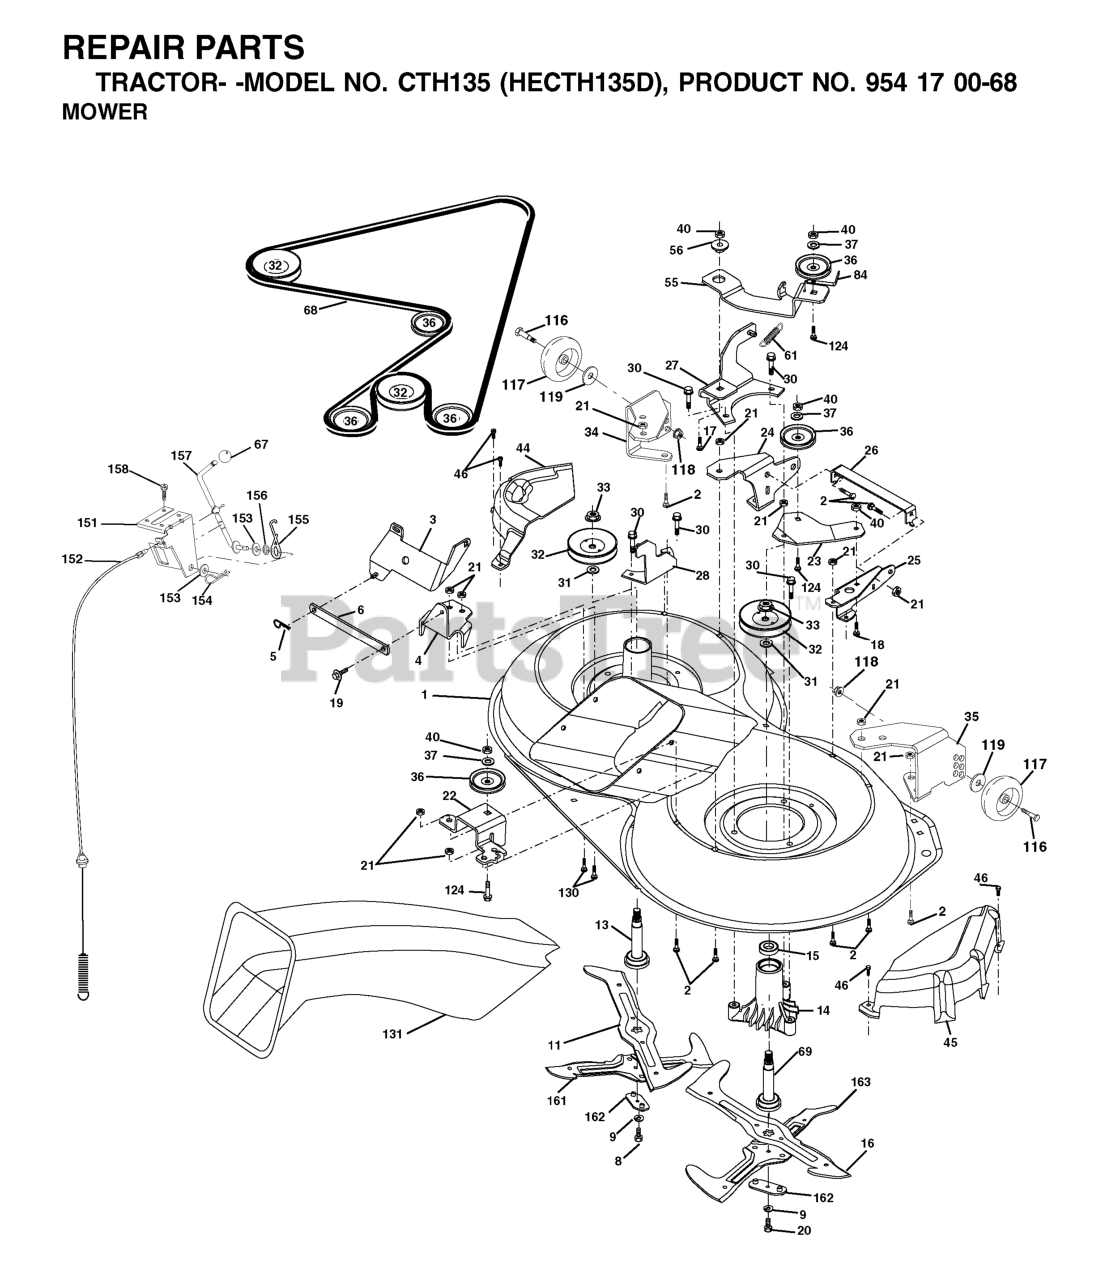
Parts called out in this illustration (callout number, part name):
1	MOWER HOUSING, DECK
2	RP BOLT 5/16-18 X3/4 ZN/YEL GR
5	RETAINER-SPRNG RB
6	BAR.SWAY.92.CRD
8	BOLT.3/8-24X1.25 GR8
9	LOCKWASHER
10	WASHER.BLADE
11	BLADE-LH 5PT STAR(CTH130)
13	SHAFT ASM VENT
14	HOUSING.MANDREL.VENTED (MACHD)
16	BLADE RH 6PT STAR(CTH130)
17	BOLT.3/8-14X1.25
18	BOLT D
19	BOLT SHD 5/16-18
20	BOLT.3/8-24X1.25GR8. LHTHRD
21	LOCKNUT
26	BRACE.SUPT.SUSP.FRT.CRD
30	SCREW, WASHER HEAD
31	WASHER
32	PULLEY, MANDREL
33	NUT, FLG TOPLOCK 9/16"
36	PULLEY.IDLER.4.25
37	WASHER
45	COVER.MANDREL.RH.CRD
46	SCREW.1/4-20X5/8
56	SPACER.RETAINER.MOWER
61	SPRING.TENSION.BELT
67	KNOB T (3/8 HOLE)
68	HEX-BELT
69	SHAFT.ASM.W/LWR.BRG.RH.THREAD
84	KEEPER, BELT IDLER
116	BOLT, SHOULDER
117	WHEEL GAGE DONUT
118	LOCKNUT
119	WASHER.5/16.FLAT.STE.STD.
124	BOLT.3/8-16X1.50
130	BOLT.CARR.SQNK.5/16-18UNC.X3/4
131	CHUTE BAGGER
151	BRACKET.CLUTCH.CABLE
153	WASHER FLAT 3/8"
154	SPRING RETAINER
155	SPRING RETENTION LEVER
156	SPACER.CLUTCH.CABLE
157	ROD CLUTCH CABLE 3/8"
158	SCREW
162	ADAPTER.BLADE.PNT.CSS.36/38/42
